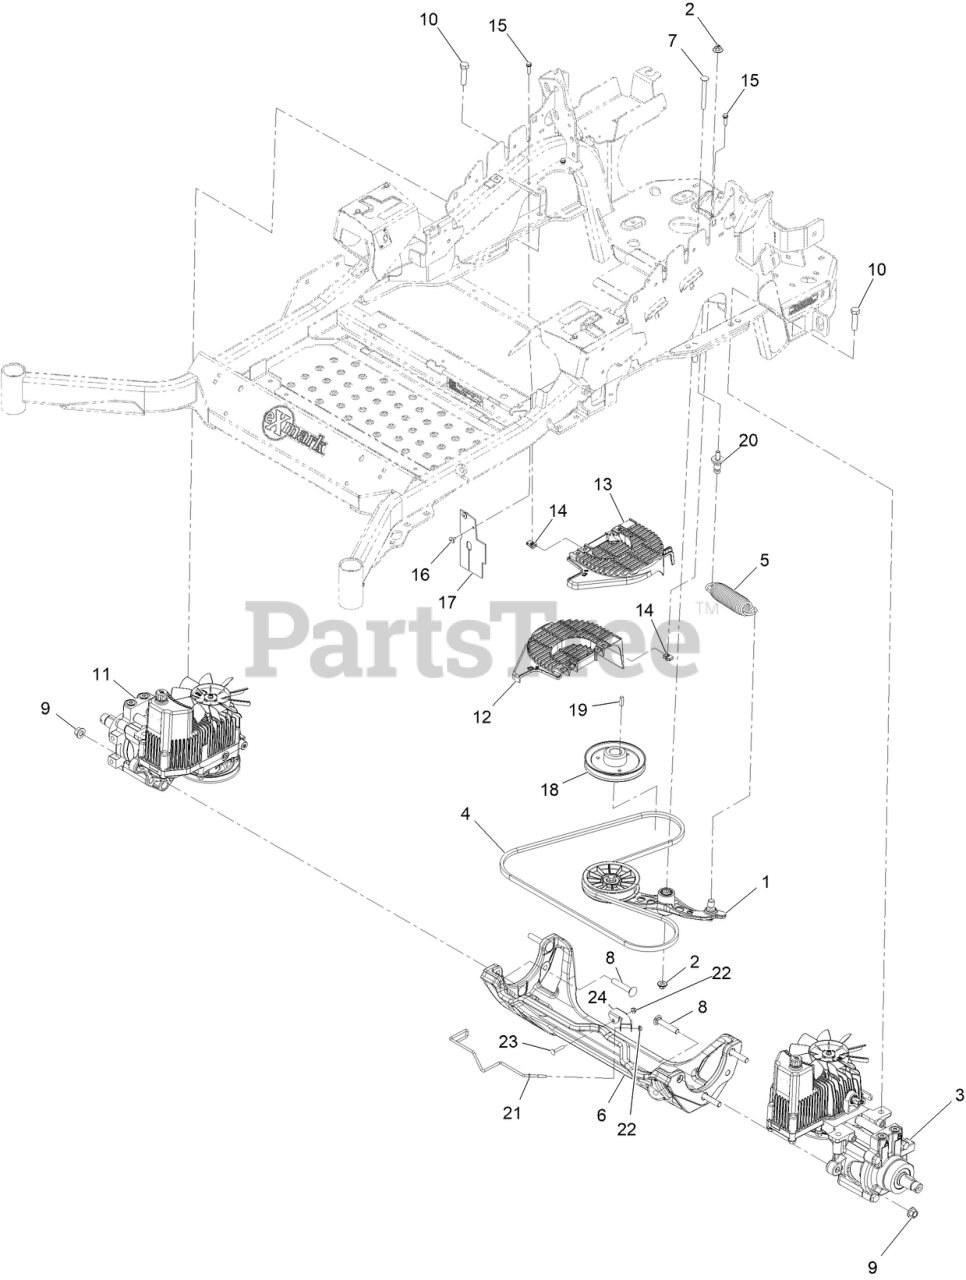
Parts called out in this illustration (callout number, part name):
1	PUMP IDLER ASM
2	Nut-Nyloc 3/8-16 Flg
3	Hydro-LH
5	SPRING-EXTENSION
6	CRADLE-HYDRO
7	BOLT-SHOULDER, CARRIAGE 3/8-16 X 3 1/2
8	SCREW-CARR
9	Nut-Lock 1/2-13
10	SCREW-HH
11	HYDRO-RH
12	Cover-Fan, Lt
13	Cover-Fan, Rt
15	SCREW-HHF
16	RIVET-POP
17	DEFLECTOR-AIR FLOW
18	SHEAVE, W/HUB
20	Pin-Spring, Anchor
21	Guide-Belt
23	SCREW-CARR
24	Bracket-U
